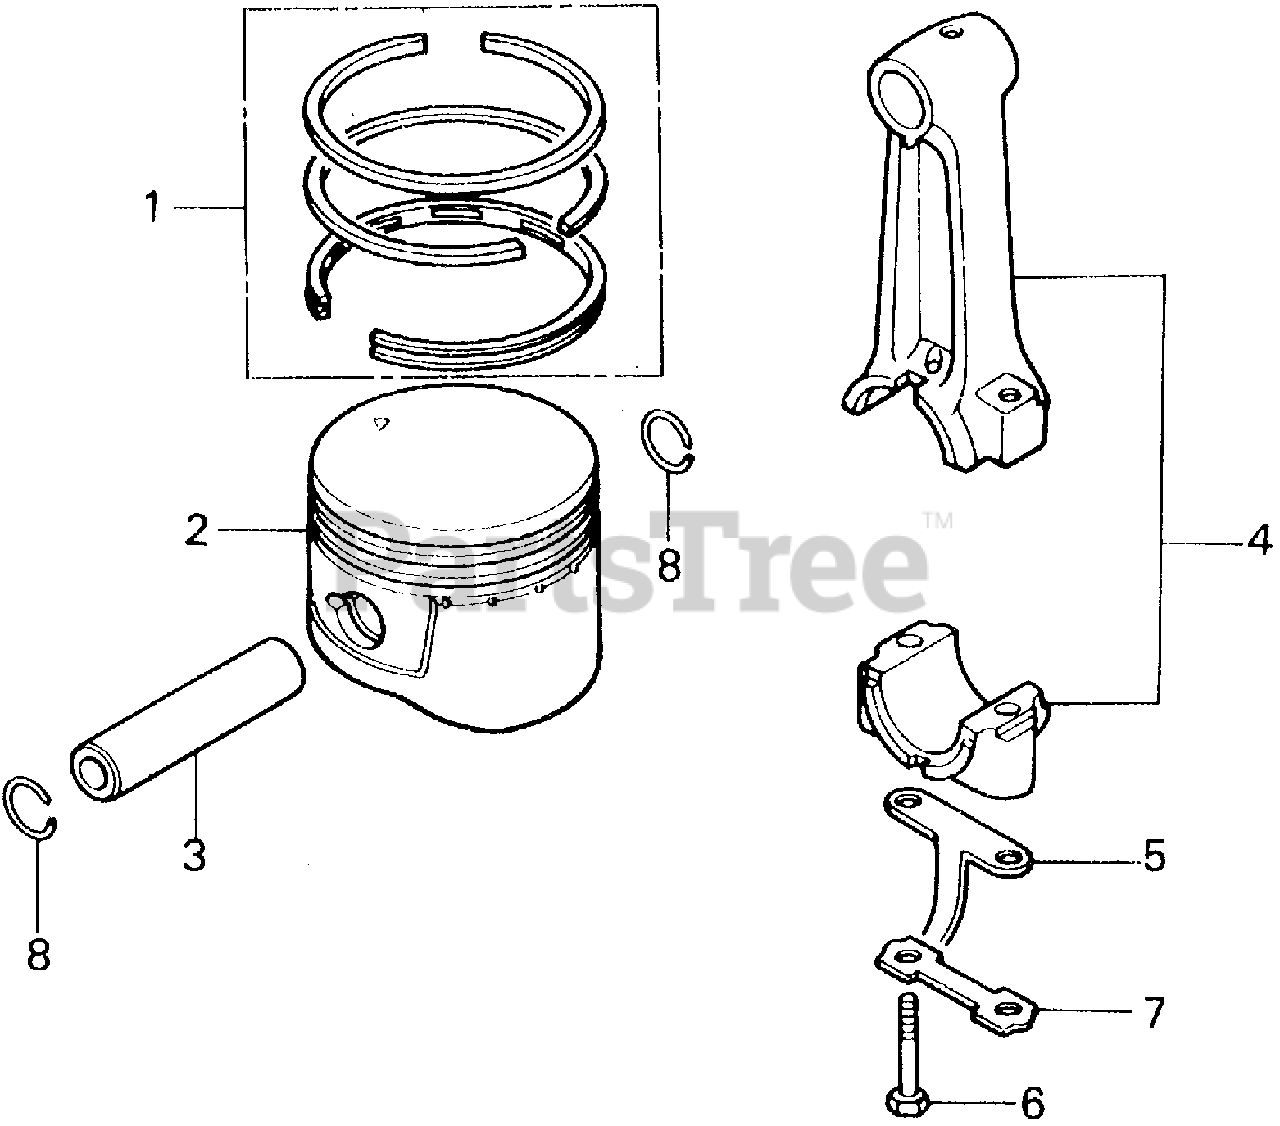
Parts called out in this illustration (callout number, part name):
1	RING SET, PISTON (STD)
1	RING SET, PISTON (OS 0.25)
1	RING SET, PISTON (OS 0.50)
1	RING SET, PISTON (0.75) (OS)
2	PISTON (STD)
2	PISTON (OS 0.25) (OS)
2	PISTON (OS 0.50) (OS)
2	PISTON (0.75) (OS)
3	PIN, PISTON
4	ROD, CONNECTING
4	ROD, CONNECTING (US)
6	BOLT, HEX. (6X37)
7	WASHER, TONGUED
8	CLIP, PISTON PIN (15MM)
